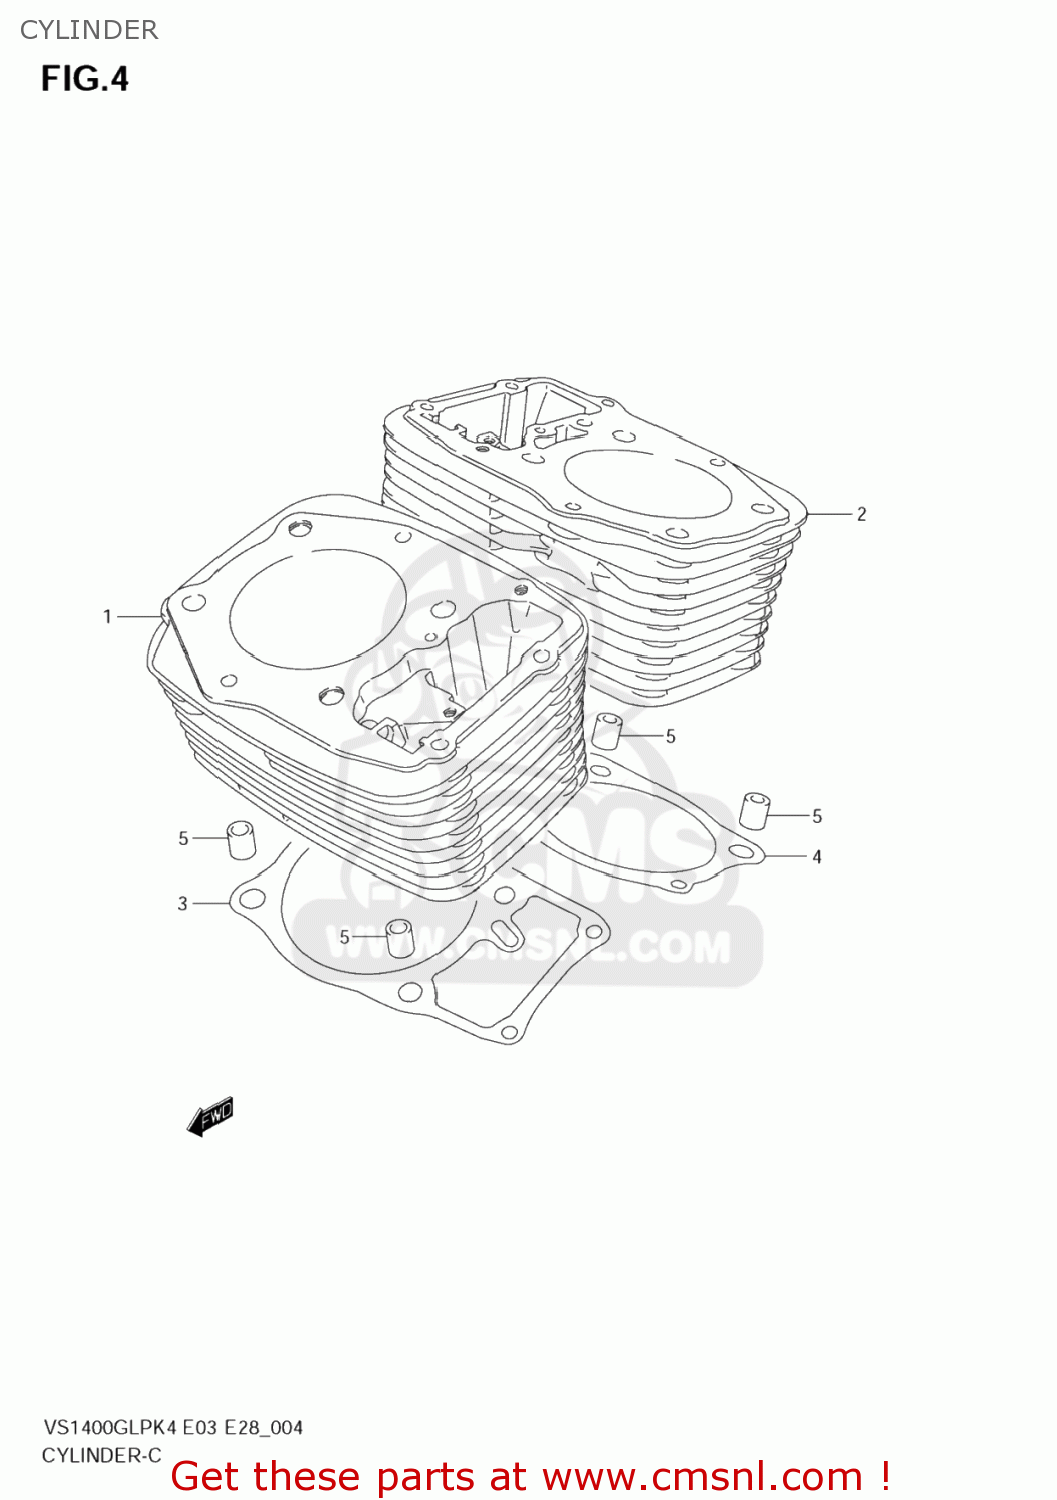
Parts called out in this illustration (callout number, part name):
1	CYLINDER,FR
2	CYLINDER,RR
3	GASKET,CYLINDER FR (NAS)
4	GASKET,CYLINDER RR (NAS)
5	PIN
